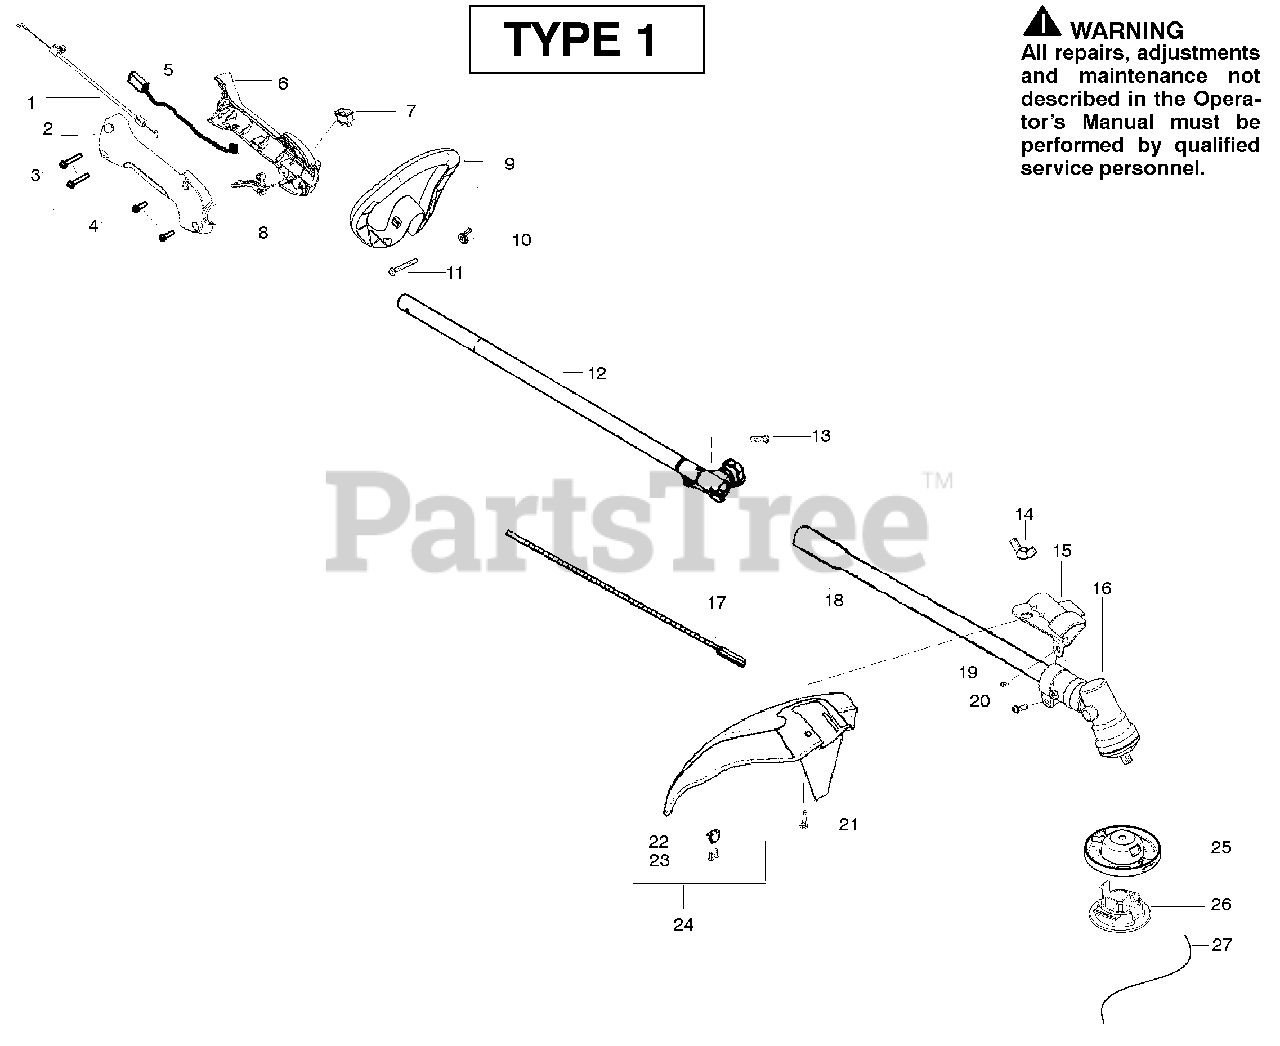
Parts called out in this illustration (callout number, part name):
1	Assy-Throttle Cable
2	Hsg.-Throttle (RH)
5	Assy.-Wire
6	Hsg. Throttle (LH)
7	Kit-Switch
8	Trigger-Throttle
9	Assy.-Handle
10	Wingnut
12	Kit-Upper Shaft
14	Wingnut
15	Bracket-Shield
17	Flexshaft-lower
18	Kit-Lower Shaft
22	Limiter-Line
24	Kit-Shield Assy.
25	Head - Fixed Line
26	Cap - Fixed Line
27	Accy - Line (12 pcs)
